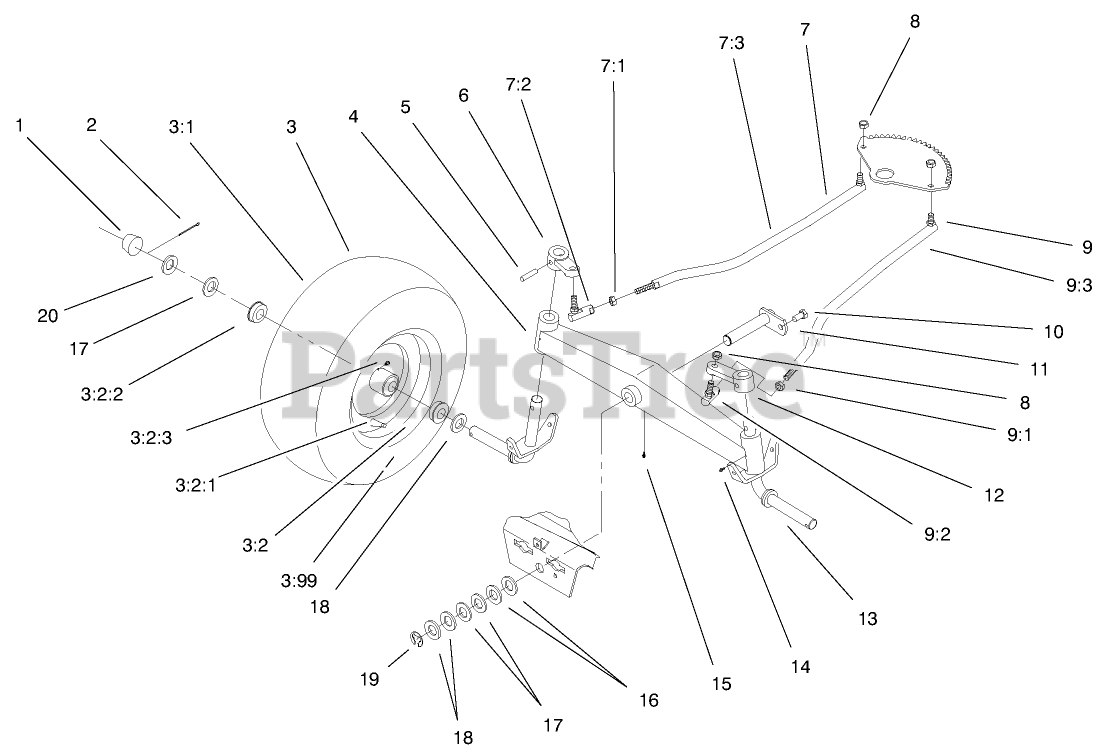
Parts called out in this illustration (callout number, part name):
1	CAP-HUB
2	PIN-COTTER
3	Wheeltire ASM,Front
3:2	WHEEL ASM
3:2:1	VALVE
3:2:2	BEARING-WHEEL
3:2:3	ZERK-GREASE
4	AXLE ASM-FRONT
7	LINKAGE-STEERING, RH
9	LINKAGE-STEERING, LH
10	SCREW-HWH, TAPTITE
11	PIN-AXLE
14	FITTING-GREASE
15	FITTING-LUBE, 45 DEG
16	WASHER
17	WASHER
18	WASHER-SHIM
19	E-RING
20	WASHER-PLAIN
